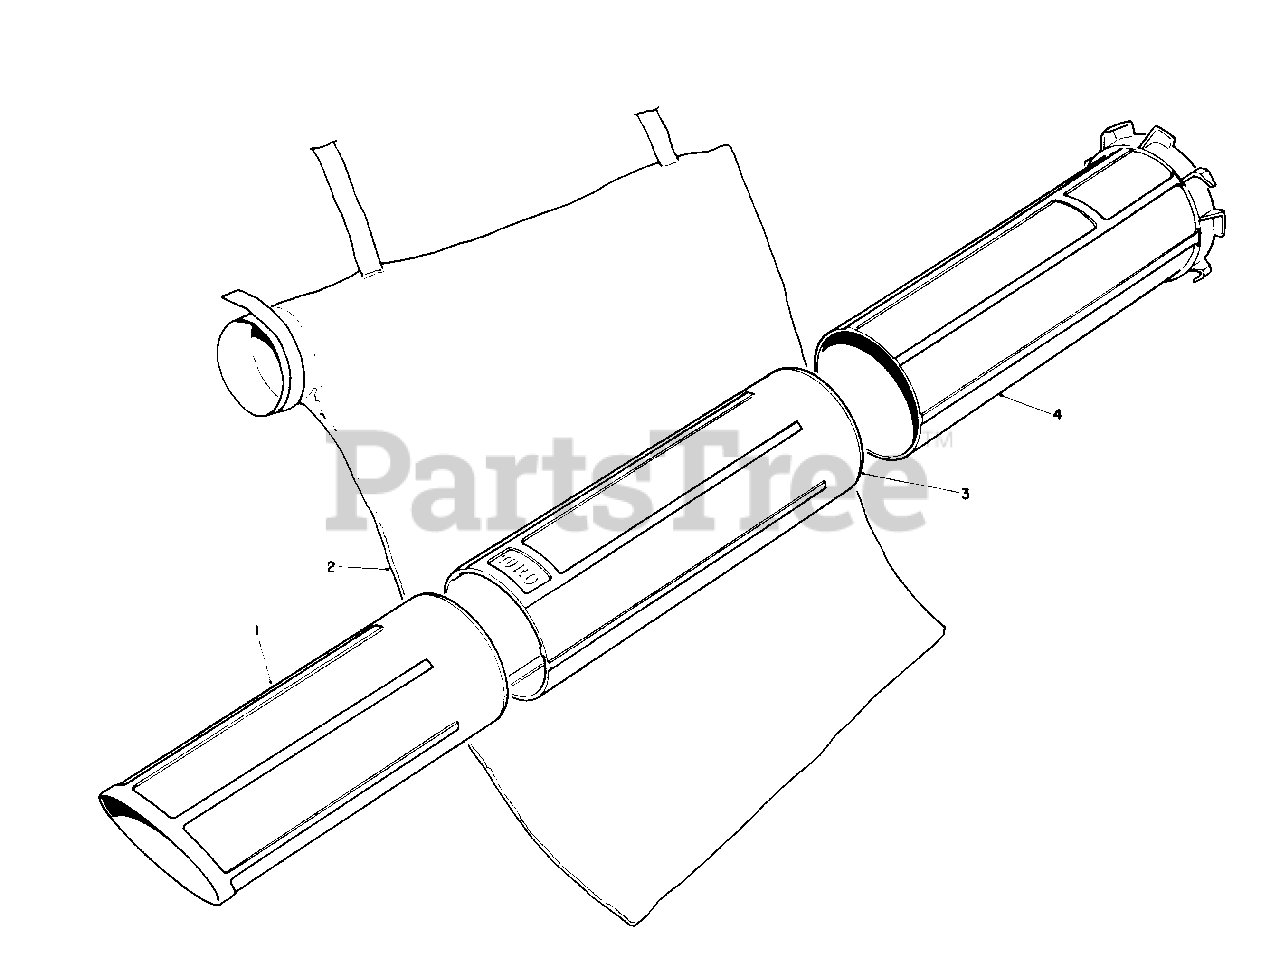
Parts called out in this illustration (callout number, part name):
1	Tube-Vacuum, Lower
2	Bag-Vacuum
3	Tube-Vacuum, Middle
4	Tube-Vacuum, Upper
